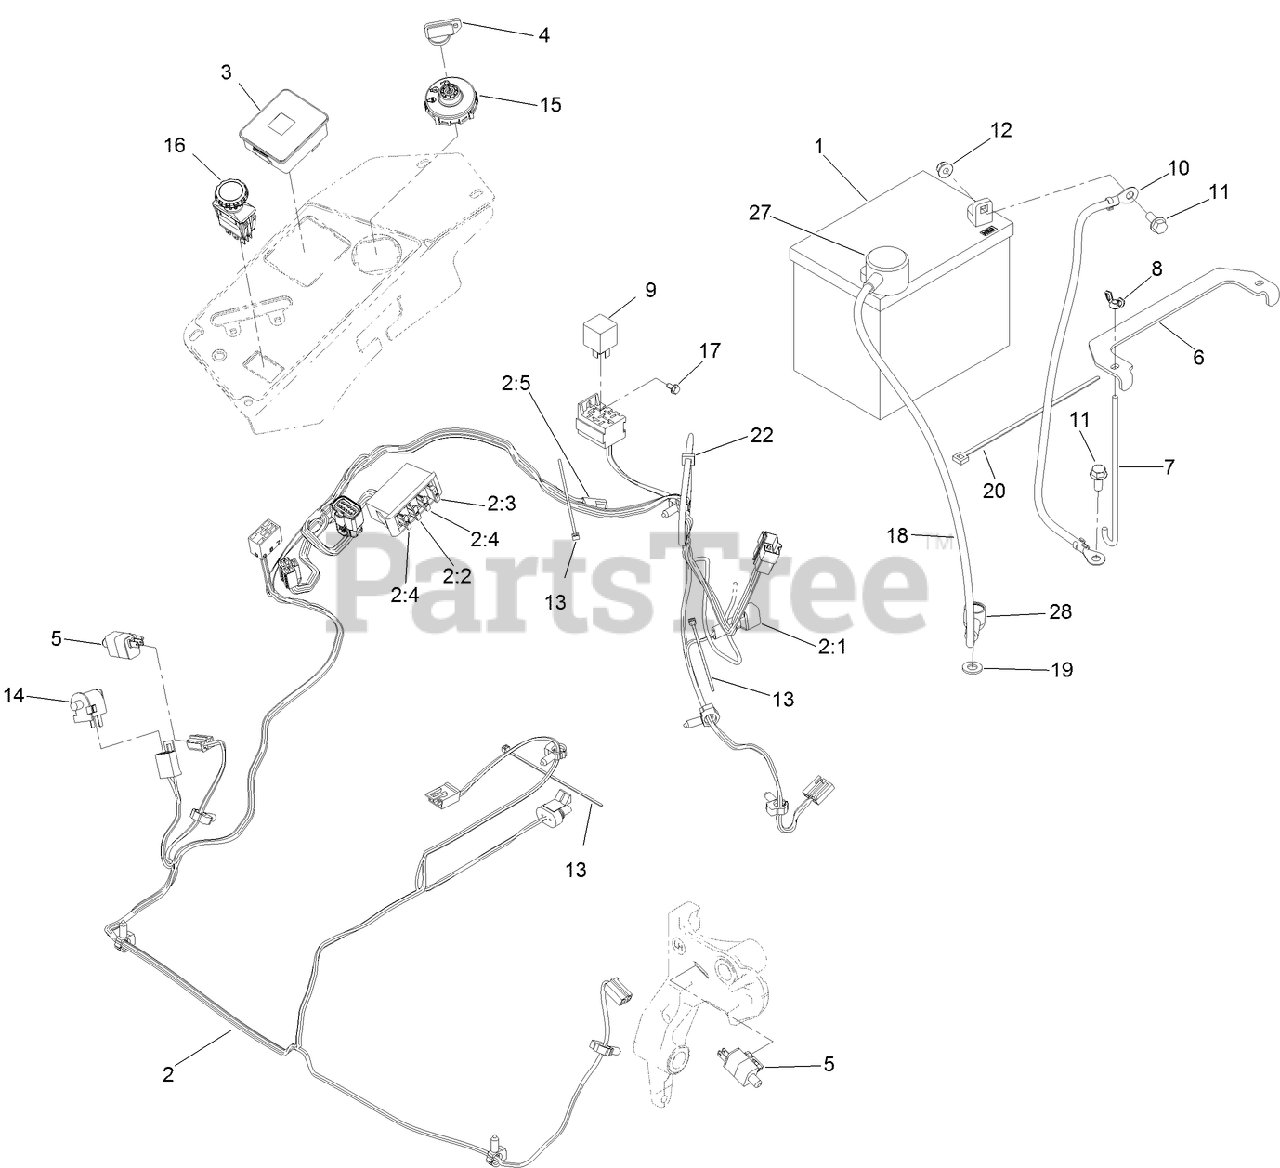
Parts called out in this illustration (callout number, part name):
1	BATTERY-DRY
2	HARNESS-WIRE, MAIN
2:2	FUSE-BLADE, 10 AMP
2:3	FUSE-BLADE, 15 AMP
2:4	FUSE-BLADE, 25 AMP
2:5	CAP-PLUG
3	FUEL/HOUR METER ASM
4	KEY-IGNITION
5	SWITCH
6	STRAP-TIE DOWN, BATTERY
7	BOLT-HOLDDOWN
8	WINGNUT
10	CABLE-BATTERY, NEGATIVE
11	SCREW-HHF
12	NUT-HF, NI
13	TIE-CABLE
14	SWITCH-BAIL
15	SWITCH-IGNITION
16	SWITCH-PTO, 10 AMP
17	SCREW-HWH
18	CABLE-BATTERY, POSITIVE
19	WASHER-FLAT
20	TIE-PLASTIC
22	TIE-PLASTIC
27	INSULATOR-BATTERY
28	INSULATOR-SOLENOID
